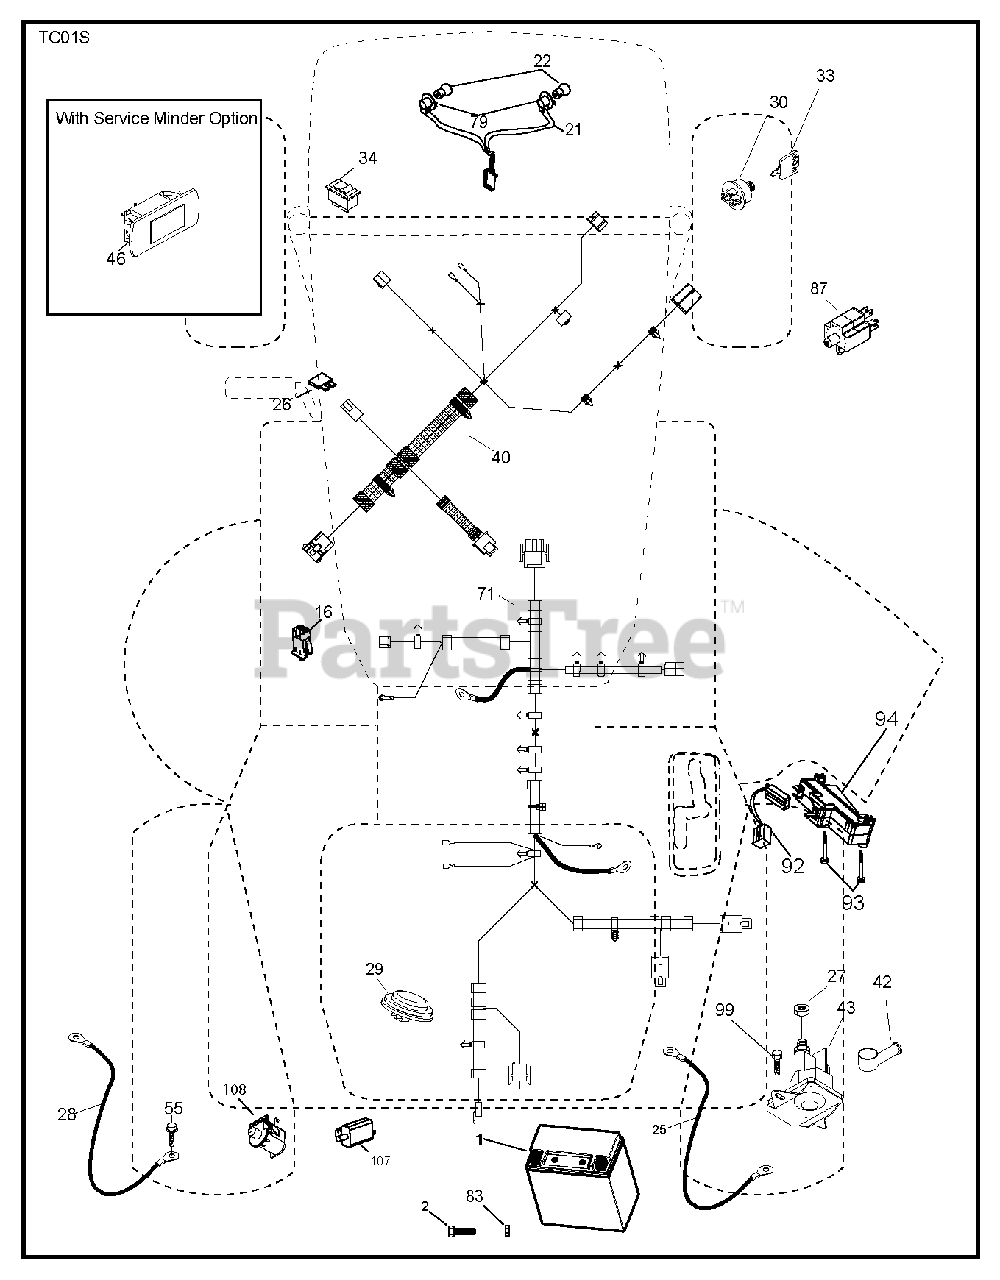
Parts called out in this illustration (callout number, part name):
16	SWITCH INTERLOOK PUSH-IN
21	HARNESS.LIGHT W/4152J BULBS
22	LIGHTBULB
26	FUSE 20AMP
27	NUT
29	SWITCH.SEAT.DELTA.OPC.
30	SWITCH.IGN.DELTA.W.LGH.ROS
33	KEY.CHAIN.BLISTER.PACK.GEN.INT
34	SWITCH LT
42	TERMINAL COVER
43	SOLENOID.W/BRASS.PLUNG
55	SCREW 5/16"
79	BULB HOLDER ASM.
92	HARNESS.PIGTAIL.CONSLE
93	SCREW.PLASTITE
94	MODULE.REVERSE.ROS
99	SCREW
108	SWITCH.SNAPMOUNT.NC
